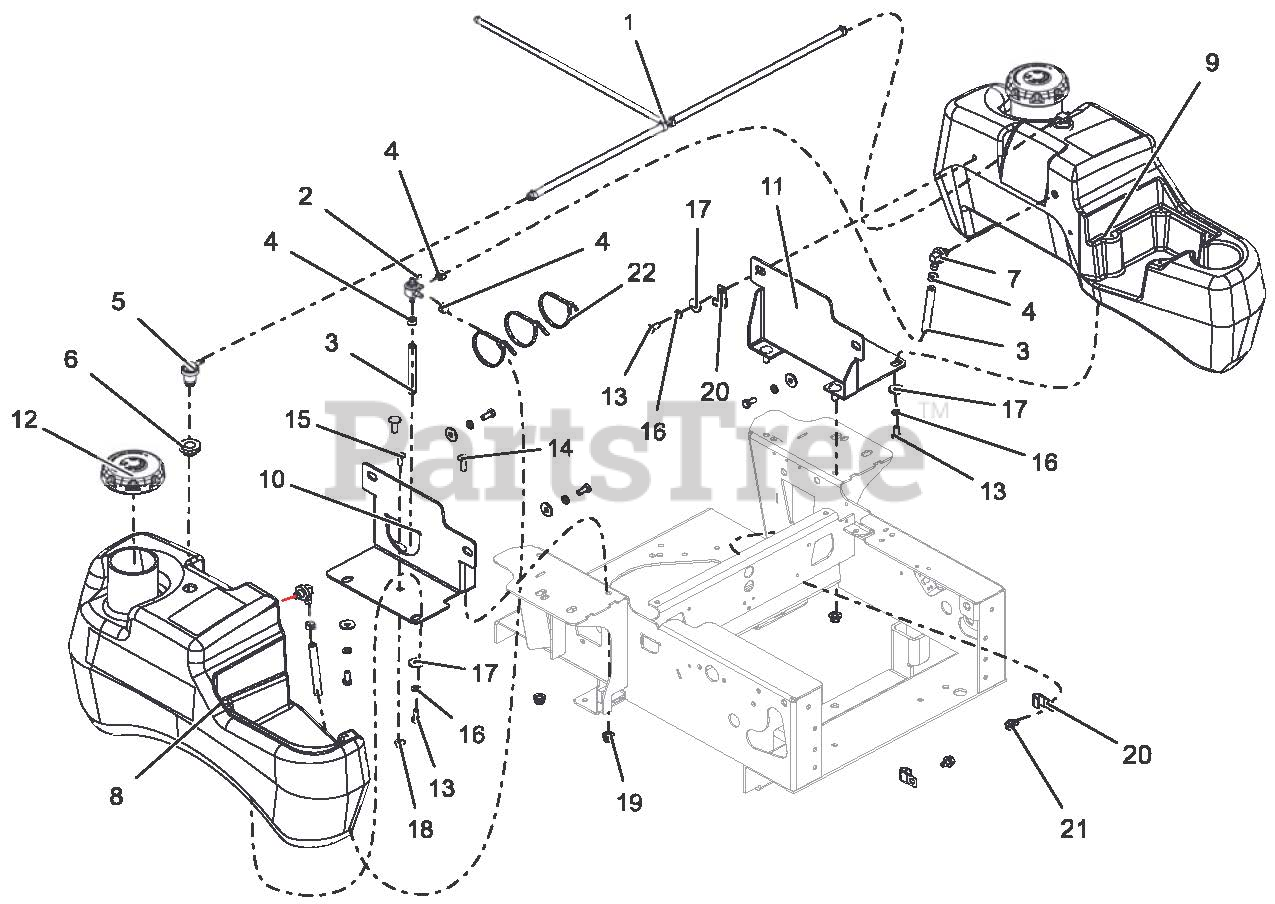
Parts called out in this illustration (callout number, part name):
1	PT100, KOHLER FUEL LINE ASSY
2	VALVE, FUEL
3	.25 LOW-PERM GAS HOSE
4	CLAMP, FUEL LINE
5	VALVE, COMBINATION
6	GROMMET, REMOTE VENT NITRILE
7	ASS'Y, SMALL/ MED TANK FUEL PICK-UP
8	TANK, GAS - RH MEDIUM GRAVELY
9	TANK, GAS - LH MEDIUM GRAVELY
10	BRKT, RH MEDIUM FUEL TANK MTG
11	BRKT, RH MEDIUM FUEL TANK MTG
12	CAP, FUEL VENT-IN AUTOLOCK
13	BLT-HEX .31-18X.75 GR5 YWZC
14	BLT-RDHDSHSQNK.38-16X1.0 G5YZ
15	BLT-RDHDSQNK .31-18X.75 G5 YWZC
16	WSHR-LK .31X.078 REG YWZC
17	WSHR-FL-STL .328X1.00X.094 YWZC
18	NUT-LK-NYL-FLG .31-18 YWZC
19	NUT-LK-NYL-FLG .38-16 YWZC
20	CLAMP, J
21	SCR-TAP .38-16X.50 HWH TR YWZ
22	CABLE, TIE 5.50 LG
